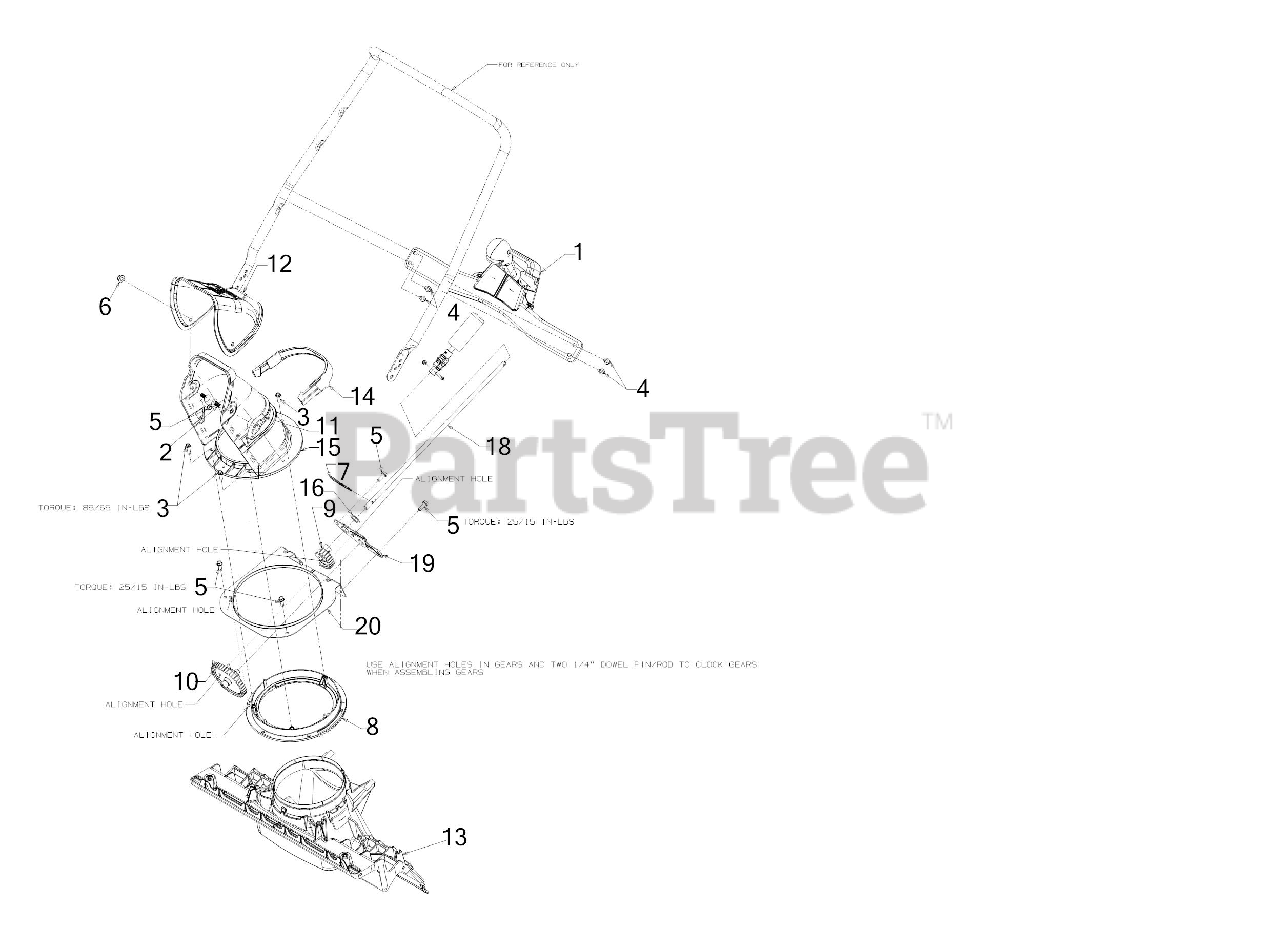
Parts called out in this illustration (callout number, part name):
1	CHUTE ROTATION HANDLE ASSEMBLY
2	CARRIAGE BOLT 5/16-18 x .75
3	SCREW 1/4 x .750
4	SCREW 1/4-20 X.500
5	SCREW 1/4-15 x .750
6	FLANGE LOCK NUT 5/16-18
7	COTTER PIN .125X2.
8	BEVEL GEAR 95T
10	SPUR-GEAR 40T
11	WING KNOB 5/16-18
12	UPPER CHUTE
13	CHUTE ADAPTER
14	CHUTE PLUG
15	LOWER CHUTE 6.5
16	FLAT WASHER .750X1.000X.060:HD
18	LOWER CHUTE CRANK ROD
19	GEAR PLATE
20	RETAIN GEAR BRACKET
